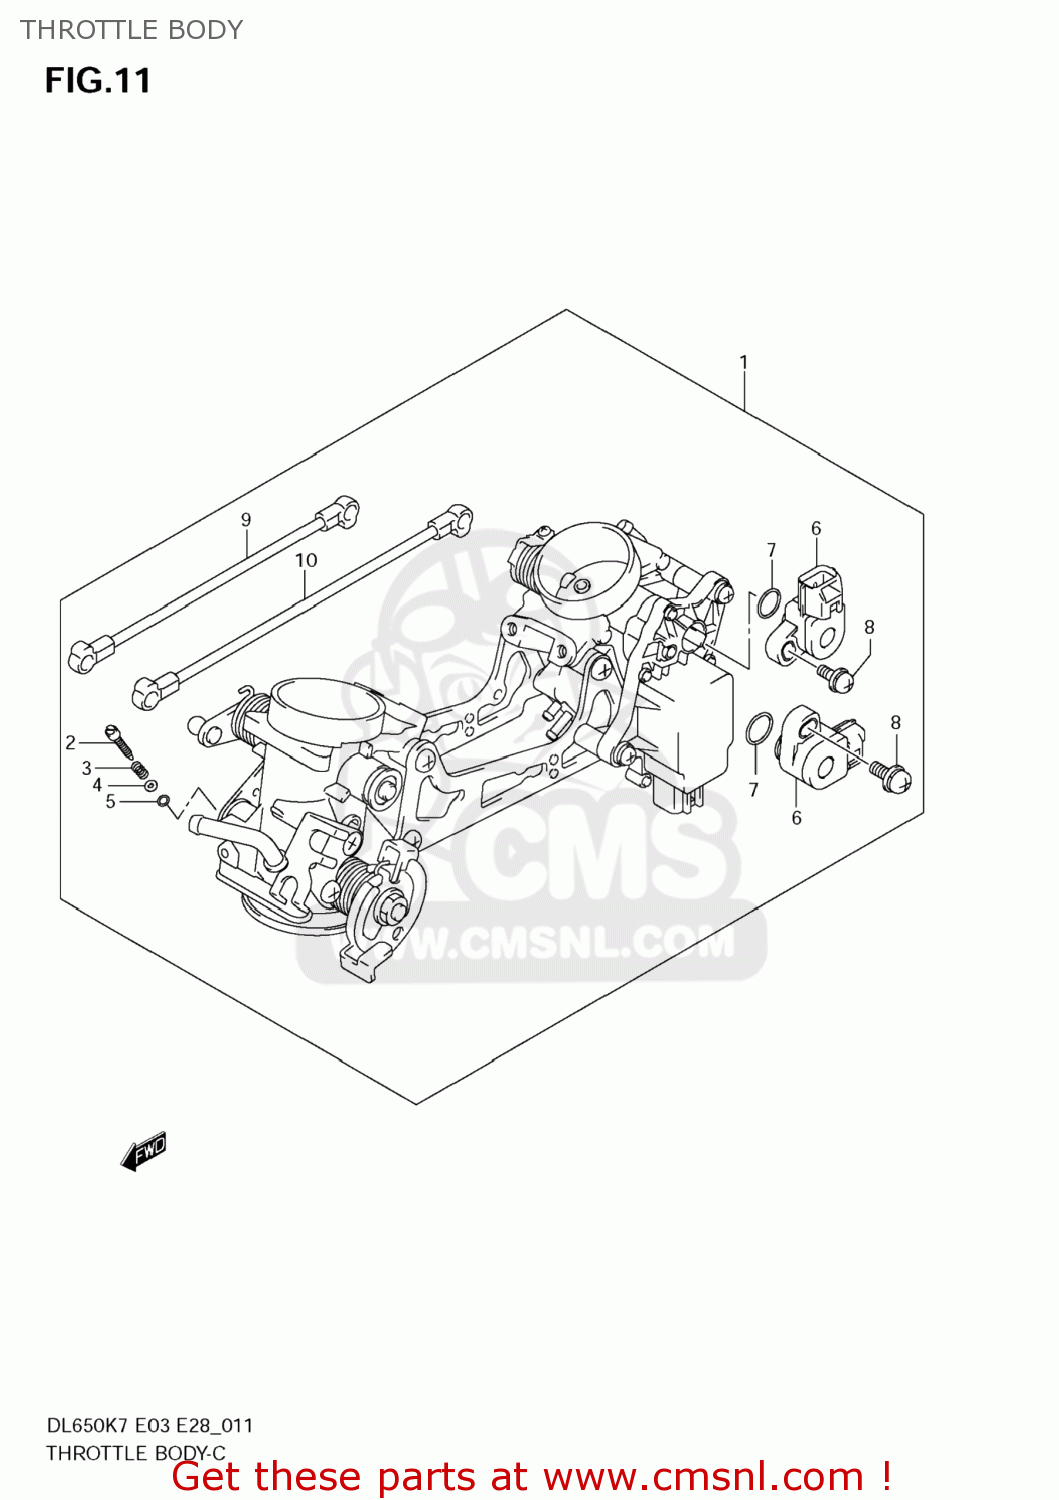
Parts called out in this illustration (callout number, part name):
1	BODY ASSY,THROTTLE
2	SCREW
3	SPRING,THROTTLE SCREW
4	WASHER
5	O RING,PILOT AIR SCREW
6	SENSOR
7	O RING
8	SCREW
9	ROD ASSY
10	ROD ASSY
